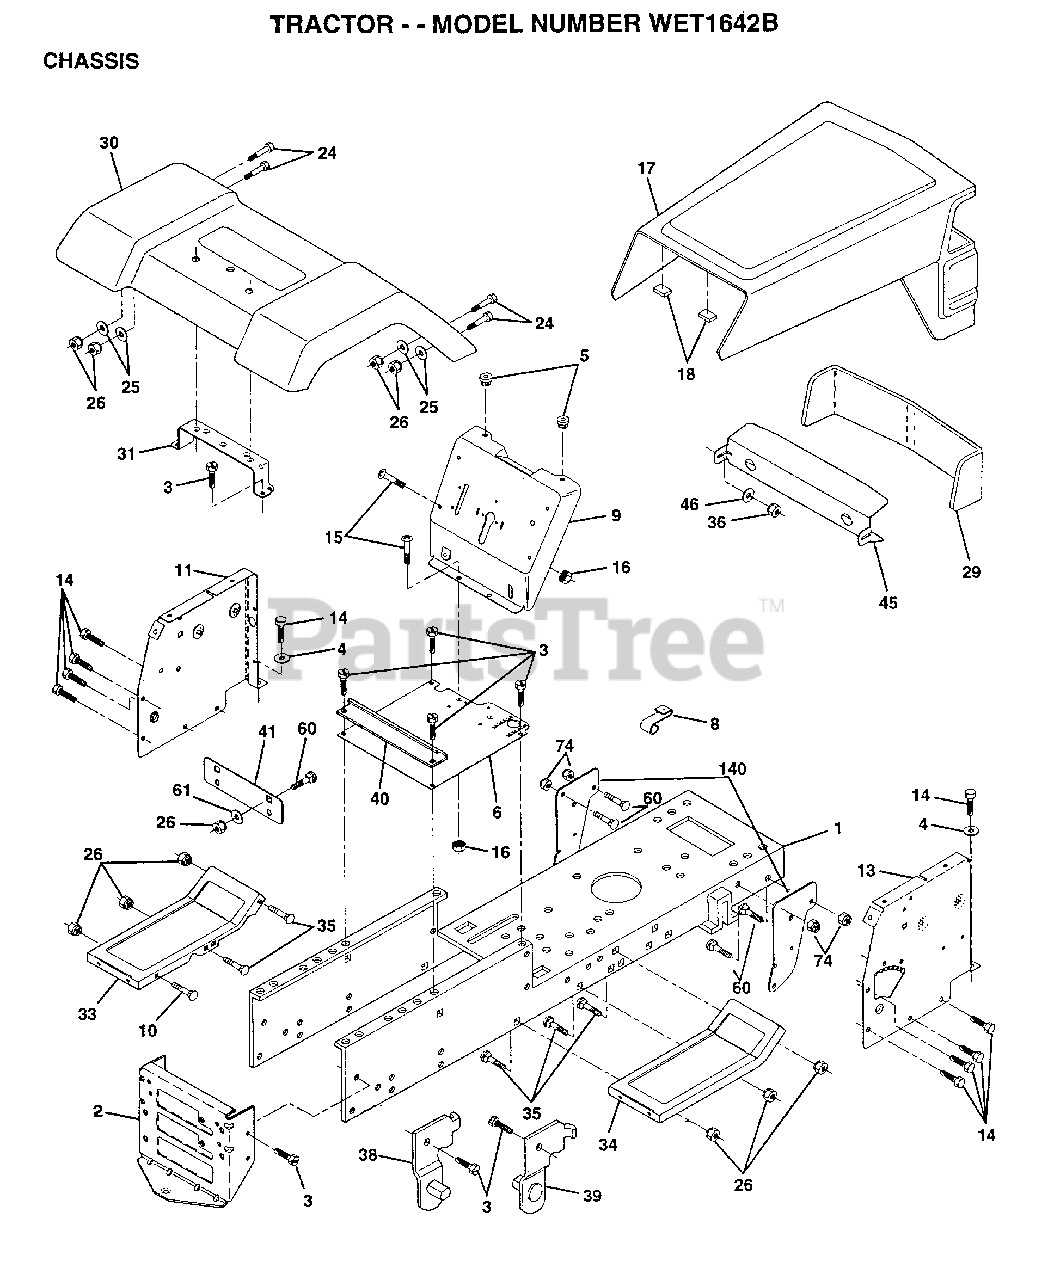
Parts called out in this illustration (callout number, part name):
1	CHASSIS WLDMT 11G
3	SCREW
4	WASHER
8	"CLIP,INSULATOR"
9	DASH.SLKSCRN.1PC.
11	PANEL.DASH.LH.
14	SCREW LT
15	SCREW
17	HOOD.W/SD.PNLS.LT
24	BOLT
25	WASHER
26	NUT
31	BRACKET SUPT FEND
33	FOOTREST.LH.LT/GT
34	FOOTREST.RH.LT/GT
35	BOLT
36	PAL NUT LT
38	BRACKET ASM LH
39	BRACKET ASM RH
40	SPACER FENDER LT
41	PLATE EXTEN FEND
46	RETAINER
60	BOLT
61	WASHER
